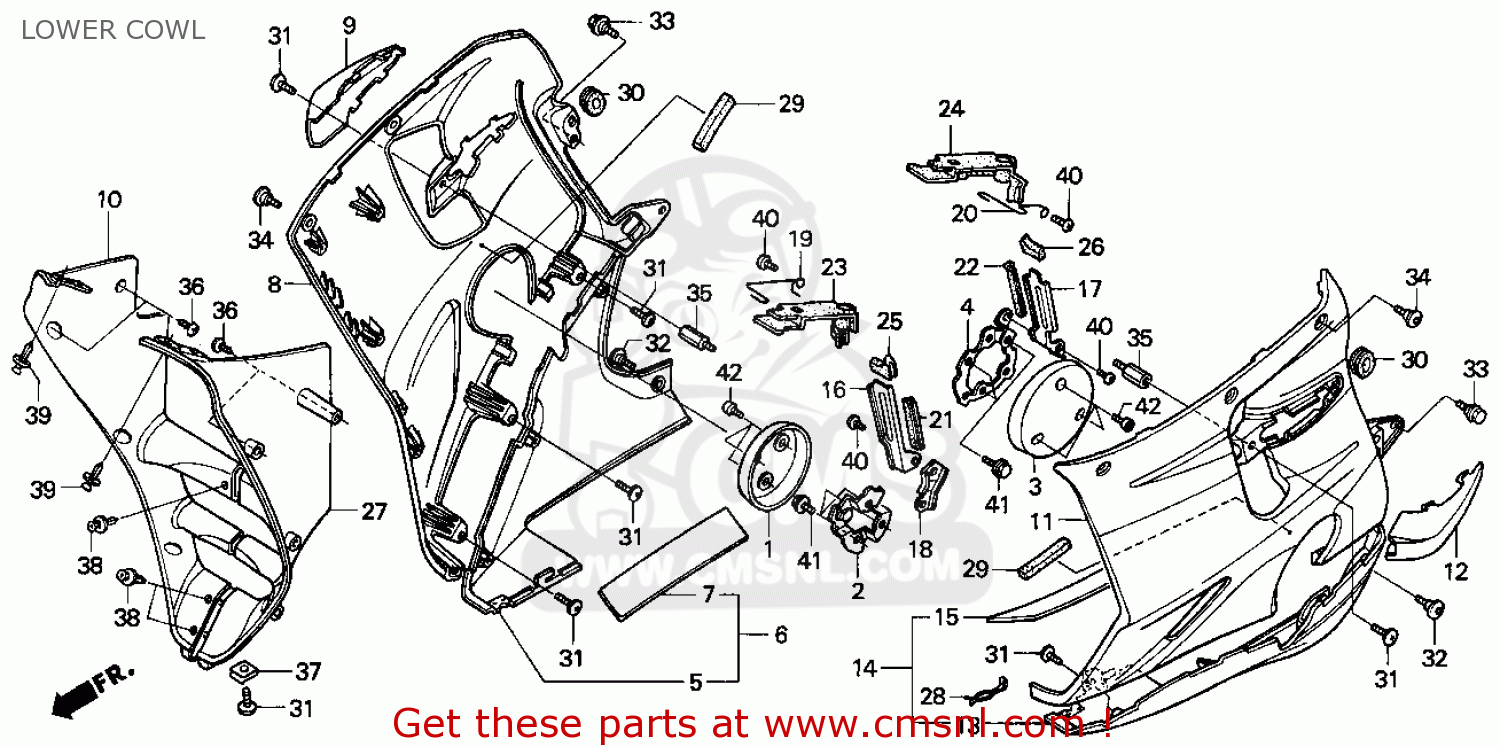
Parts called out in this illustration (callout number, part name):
1	PROTECTOR COMP.,R
2	STAY,R.COVER PROT
3	PROTECTOR COMP.,L
4	STAY,L.COVER PROT
5	COWL,R.UN*NH206M*
6	COWL,R.UN*NH206M*
7	SHEET,R.UNDER COW
8	SET ILLUS*TYPE15*
9	PROTECTOR R *NH1*
10	INNER,R.MIDD*NH1*
11	SET ILLUS*TYPE15*
12	PROTECTOR,L.*NH1*
13	COWL,L.UN*NH206M*
14	COWL,L.UN*NH206M*
15	SHEET,L.UNDER COW
16	SEPARATE,R.MIDDLE
17	SEP.,L MID COWL A
18	STAY,R.MIDDLE COW
19	WIRE,R.SEPARATE R
20	WIRE,L.SEPARATE R
21	RUBBER,R.MIDDLE C
22	RUB L MID COWL SE
23	RUBBER A,R.
24	RUBBER A,L.
25	RUBBER B,R.
26	RUBBER B,L.
27	INNER,L.MIDD*NH1*
28	SPG.,COWL SET
29	RUBBER,SEAL
30	GLOM,SIDE COVER
31	SCREW,SPECIAL,5X1
32	SCREW,PAN,6X11
33	BOLT,FLANGE,6MM
34	SCREW,PAN,6X14
35	BOLT MIDD.COWL
36	SCREW,TRUSS (METE
37	NUT,CLIP,5MM
38	CLIP, SPLASH SHIELD
39	CLIP,BODY COVER
40	SCREW,CROSS,6X10
42	BOLT,SOCKET
